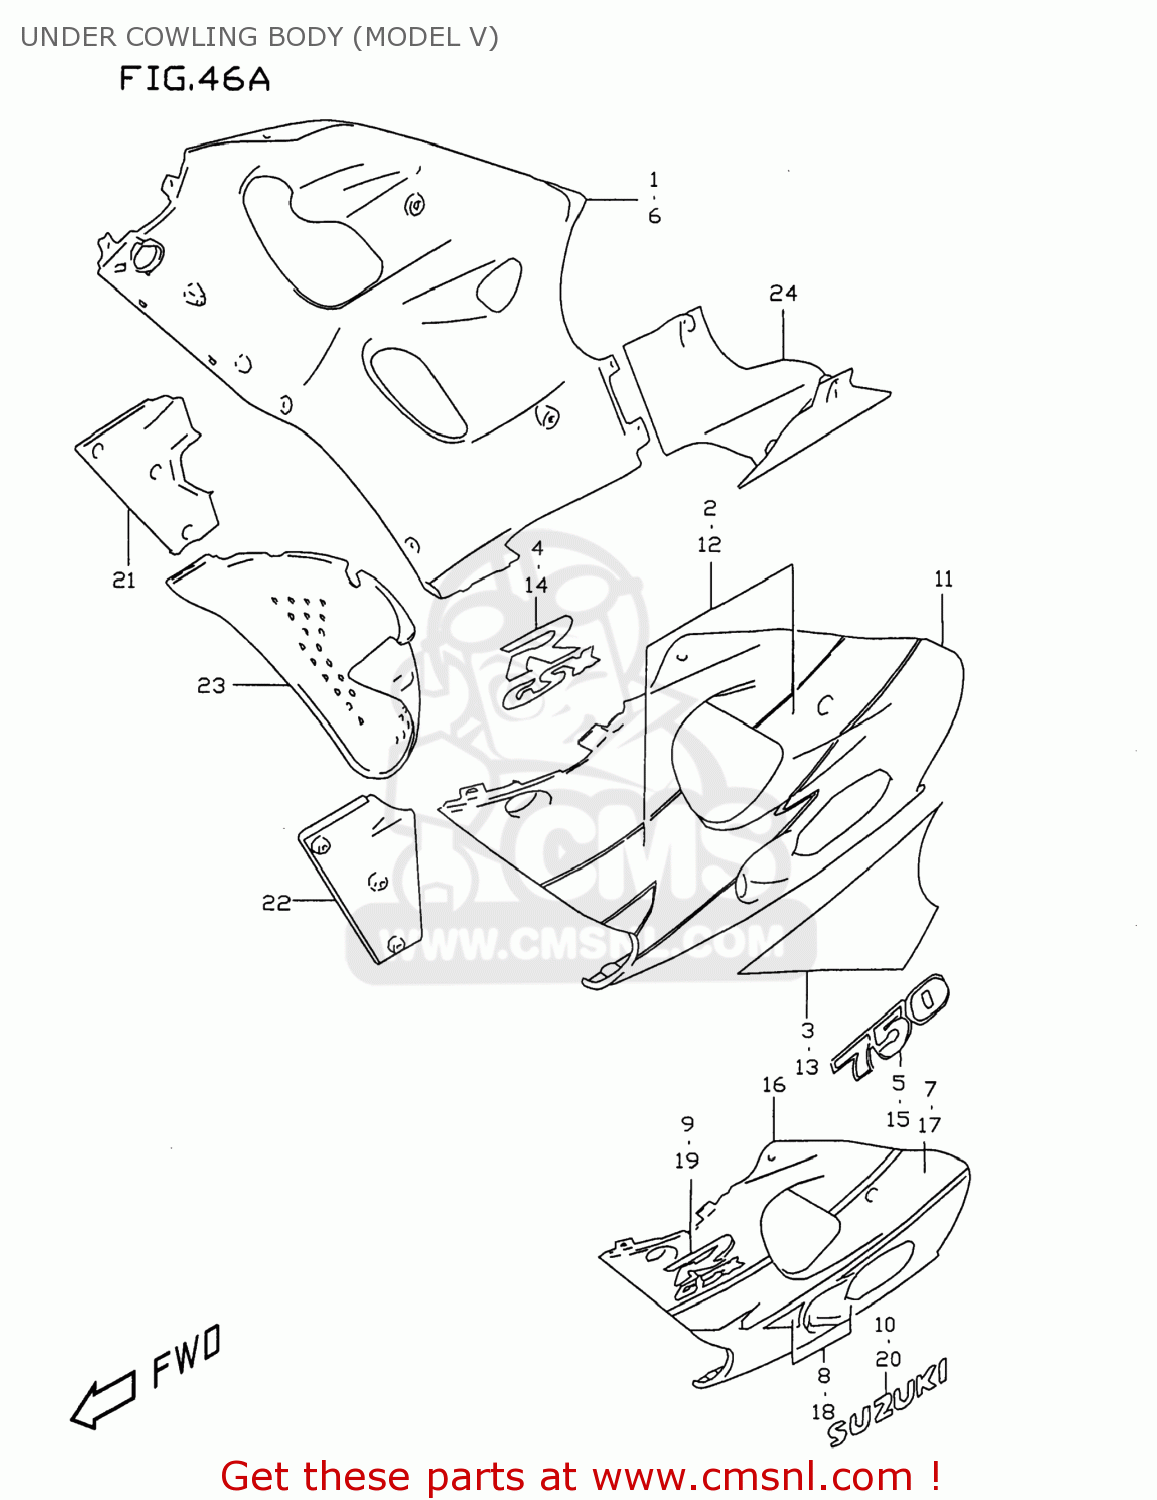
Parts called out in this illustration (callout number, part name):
1	COWLING ASSEMBLY,UNDER,RIGHT
2	TAPE SET,COWLING,UNDER,RIGHT
3	TAPE,COWLING,UNDER,RIGHT
4	EMBLEM,COWLING UNDER
5	EMBLEM,COWLING,UNDER
6	COWLING ASSEMBLY,UNDER,RIGHT
7	TAPE,COWLING,UNDER,UPPER
8	TAPE SET,COWL LWR,R
9	EMBLEM,COWLING UNDER
10	EMBLEM,SUZUKI(BLUE)
11	COWLING ASSEMBLY,UNDER,LEFT
12	TAPE SET,COWL UNDER,L
13	TAPE,COWL UNDER,L
14	EMBLEM,COWLING UNDER
15	EMBLEM,COWLING,UNDER
16	COWLING ASSEMBLY,UNDER,LEFT
17	TAPE,COWL UNDER UPR,L
18	TAPE SET,COWL LWR,L
19	EMBLEM,COWLING UNDER
20	EMBLEM,SUZUKI(BLUE)
21	COWLING,UNDER INNER,R
22	COWLING,UNDER,INNER,LEFT
23	COWLING,UNDER,CENTER
24	COWLING ASSEMBLY,UNDER,REAR
